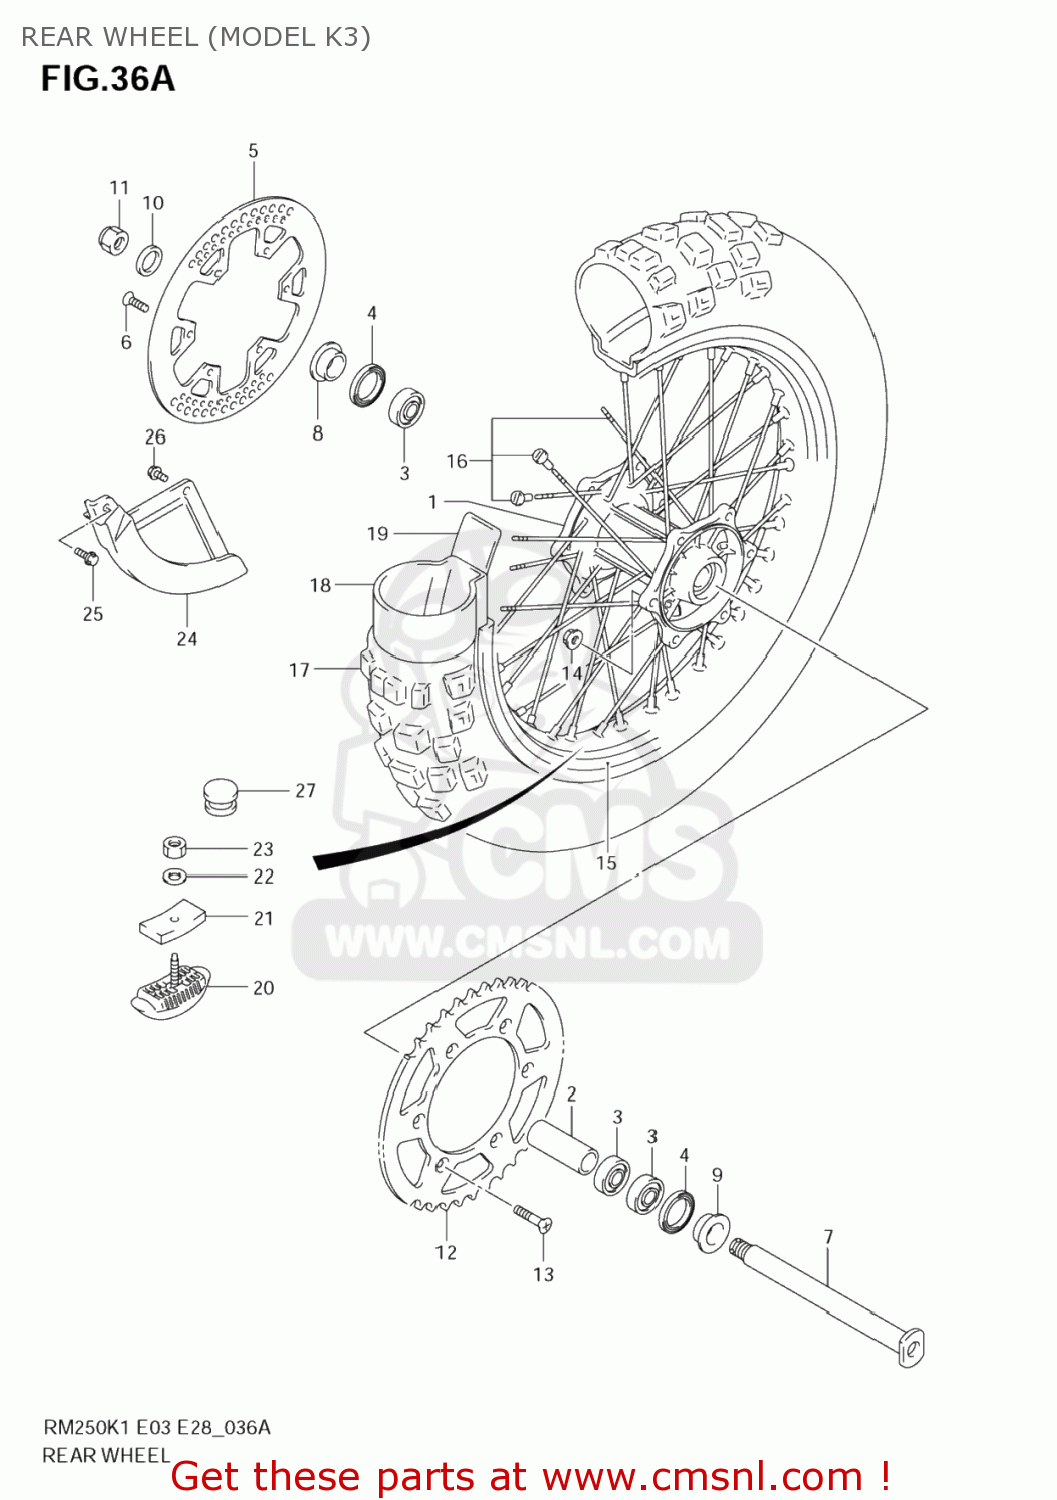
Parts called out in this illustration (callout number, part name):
1	HUB,RR WHEEL
2	SPACER,RR HUB BEARING
3	BEARING(22X44X12)
4	SEAL,OIL(30X44X7)
5	DISC,RR BRAKE
6	SCREW
7	AXLE,RR
8	SPACER,RR AXLE
9	SPACER,RR AXLE
10	WASHER(19X32X3.2)
11	NUT
12	SPROCKET,RR(NT:49)
13	BOLT(8X30.5)
14	NUT
15	RIM,RR WHEEL(2.15X19 AL.)
16	SPOKE SET,RR WHEEL
17	TIRE,RR(110/90 19)
18	TUBE ASSY,WHEEL INNER
19	PROTECTOR,WHL INR TUBE
20	STOPPER,BEAD(2.15)
21	CUSHION,BEAD STOPPER
22	WASHER
23	NUT
24	COVER,REAR DISC
25	BOLT
26	BOLT
27	CAP(OD:12)
